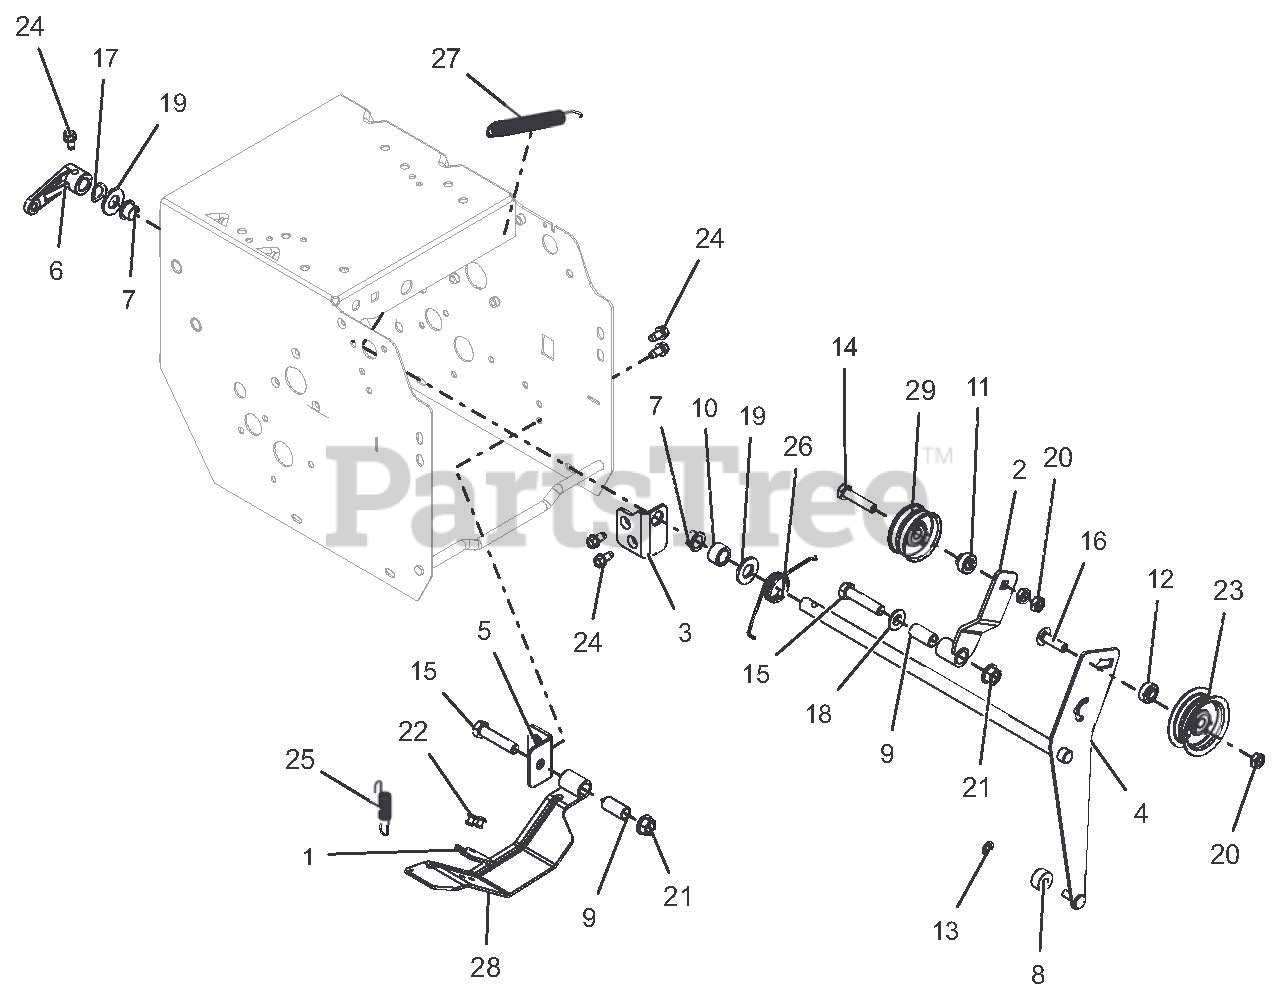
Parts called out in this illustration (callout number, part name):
1	PAD, BRAKE
2	ARM, TRACTION IDLER
3	BRACKET, MOUNT - IDLER ARM
4	WELDMENT, ATTACHMENT IDLER ARM
5	BRACKET, MOUNT - BRAKE
6	ARM, CLUTCH - ATTACHMENT
7	BUSHING, POLYLINER-.50 SPLIT
8	BSHG,SLV .265 X .625 X .375
9	BSHG-SLV .385X.500X1.045
10	BSHG-SLV .510X.751X.475
11	SPCR, BRG .315X.500X.481X.281
12	SPCR, BRG .315X.500X.358X.281
13	RG-RTNG-EXT .250X.010
14	@BLT-HEX .31-18X1.50 GR5 YWZC
15	@BLT-HEX .38-16X1.75 GR5 YWZC
16	BLT-RDHDSQSHNK.31-18X1.13 G5YZ
17	WSHR-WAVE .50X.75X.015 .13FRHT
18	@WSHR-FL-STL.406X.812X.065 YWZ
19	@WSHR-FL-STL.531X1.06X.095YWZC
20	@NUT-LK-CTR-JAM .31-18 YWZC
21	@NUT-LK-TOP-FLG .38-16 YWZC
22	RVT-POP .187 YZ
23	IDLER, FLAT - 2.00"
24	SCR-TAP .25-20X.50 HWH TR YWZ
25	SPRING-EXT .437 X .438 X 2.64
26	SG-TORS .075 X .955
27	SPRING, EXTENSION
28	BRAKE ARM W/PAD
29	IDLER, FLAT - 1.875"
